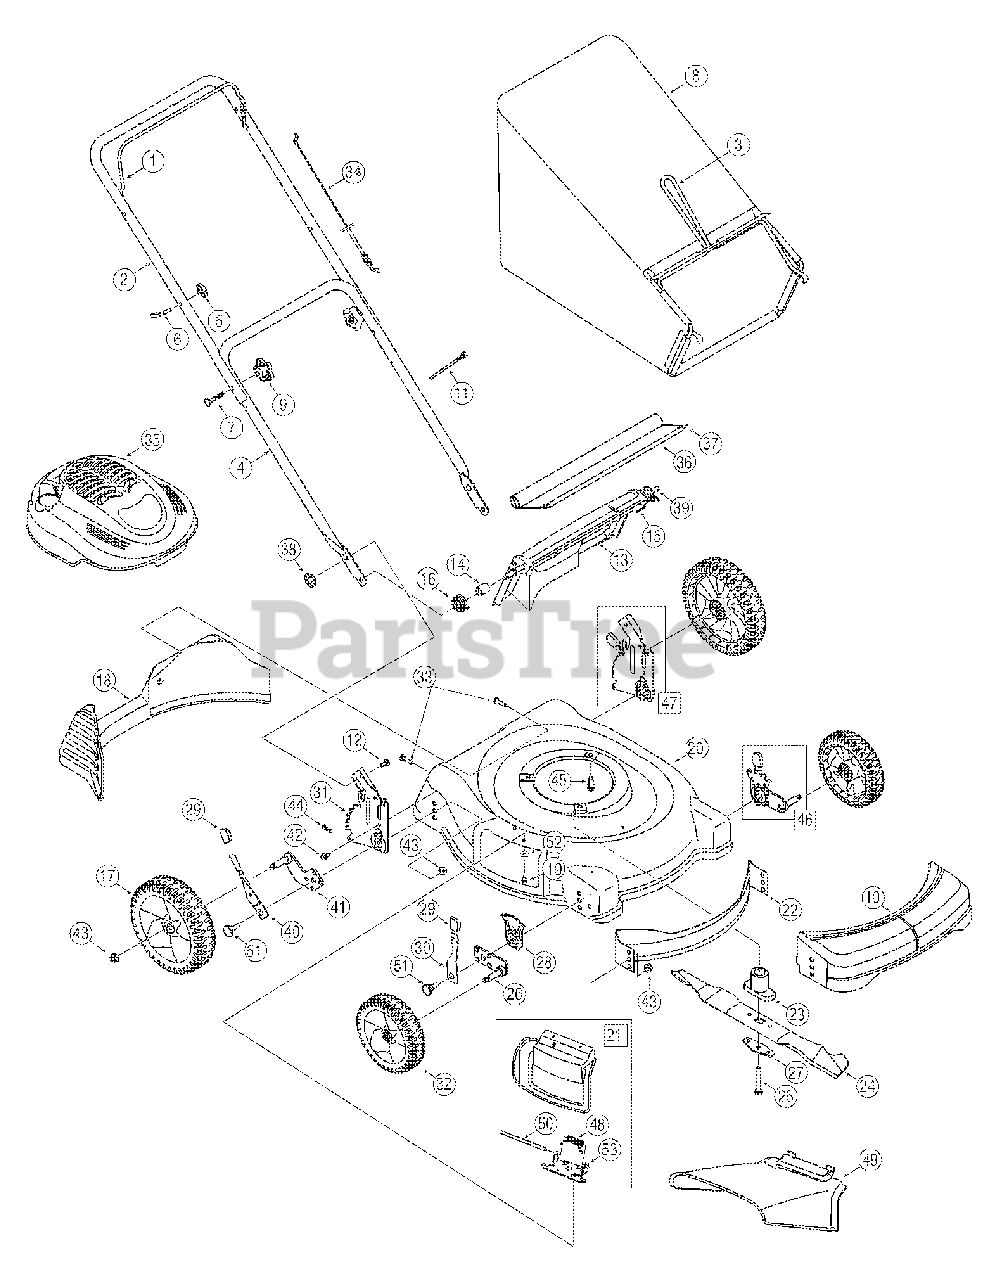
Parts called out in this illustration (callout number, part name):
5	Wing Nut
6	Rope Guide
7	Carriage Bolt ,5/16-18 x 2
8	Grass Bag Assembly
9	Hand Knob
10	Front Cover
11	Cable Tie
12	Carriage Bolt ,1/4-20
13	Rear Discharge Door
14	Spacer
15	Torsion Spring - LH
16	Torsion Spring - RH
17	Rear Wheel, 8 x 1.8
18	Rear Baffle
19	Screw, 1/4-20 x .500
22	Front Baffle
23	Blade Adapter #6 x 2.15"
23	Blade Adapter 25mm x 2.15"
24	Mulching Blade
25	Hex Screw , 3/8-24 x 2.5
26	Pivot Arm Assembly -RH
27	Blade Bell Support
28	Front Adjustment Plate
29	Adjustment Lever Knob
30	Spring Lever Assembly
31	Handle Bracket - RH
32	Front Wheel, 7 x 1.8
33	Screw, 1/4-15 x 1.250
34	Control Cable - 53" Snap On
35	Engine Shroud
36	Trailshield
37	Trailshield Wire
38	Wing Nut, 1/4-20
39	Rear Door Pivot Rod
40	Spring Lever
41	Pivot Arm Assembly - RH
42	AB Screw
43	Flange Lock Nut, 3/8-16
44	Hairpin Clip
45	TT Sems Screw, 3/8-16 x 1.0
46	Ht. Adj. Assy. Front - LH
47	Rear Handle Bracket Assy. - LH
48	Torsion Spring
49	Side Chute
50	Hinge Pin
51	Shoulder Screw
52	Bell Washer
53	Deflector Chute Adaptor
